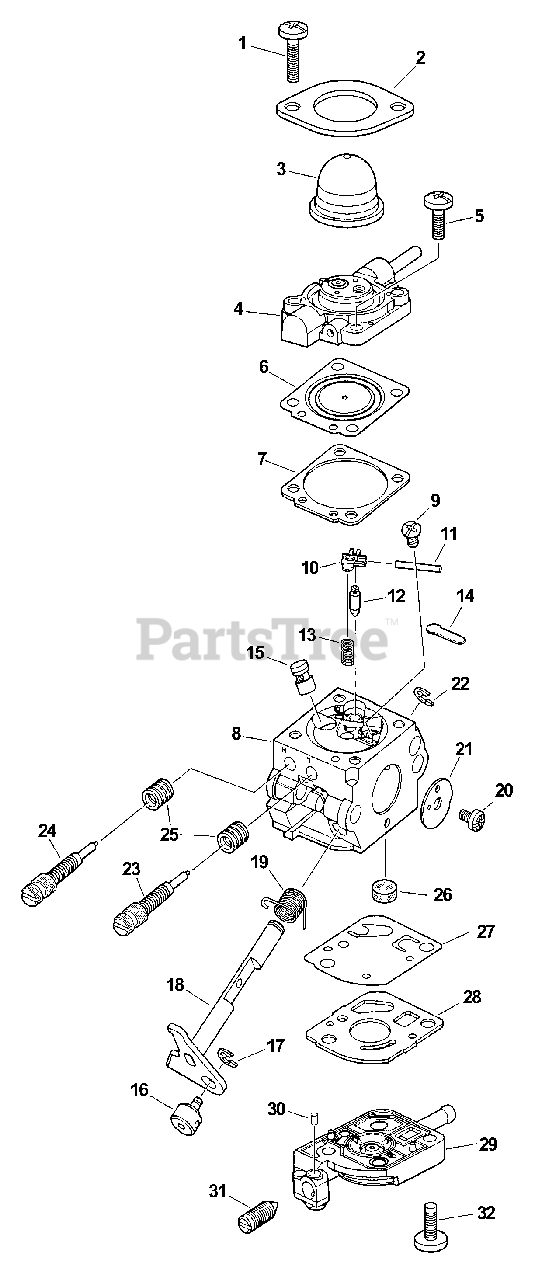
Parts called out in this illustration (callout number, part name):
2	RETAINER, PURGE BULB
3	BULB, PURGE
4	BODY ASSY, PURGE
6	DIAPHRAGM, METERING
7	GASKET, METERING
8	BODY, CARBURETOR
9	SCREW, METERING LEVER PIN
10	LEVER, METERING
11	PIN, METERING LEVER
12	VALVE, INLET NEEDLE
13	SPRING, METERING LEVER
14	PLUG, WELCH
15	NOZZLE, CHECK VALVE
18	SHAFT, THROTTLE
19	SPRING, THROTTLE RETURN
21	VALVE, THROTTLE
23	NEEDLE, IDLE
24	NEEDLE, HIGH SPEED
25	SPRING, NEEDLE
26	STRAINER
29	COVER, PUMP
30	PIECE, FRICTION
31	SCREW, IDLE ADJUST
